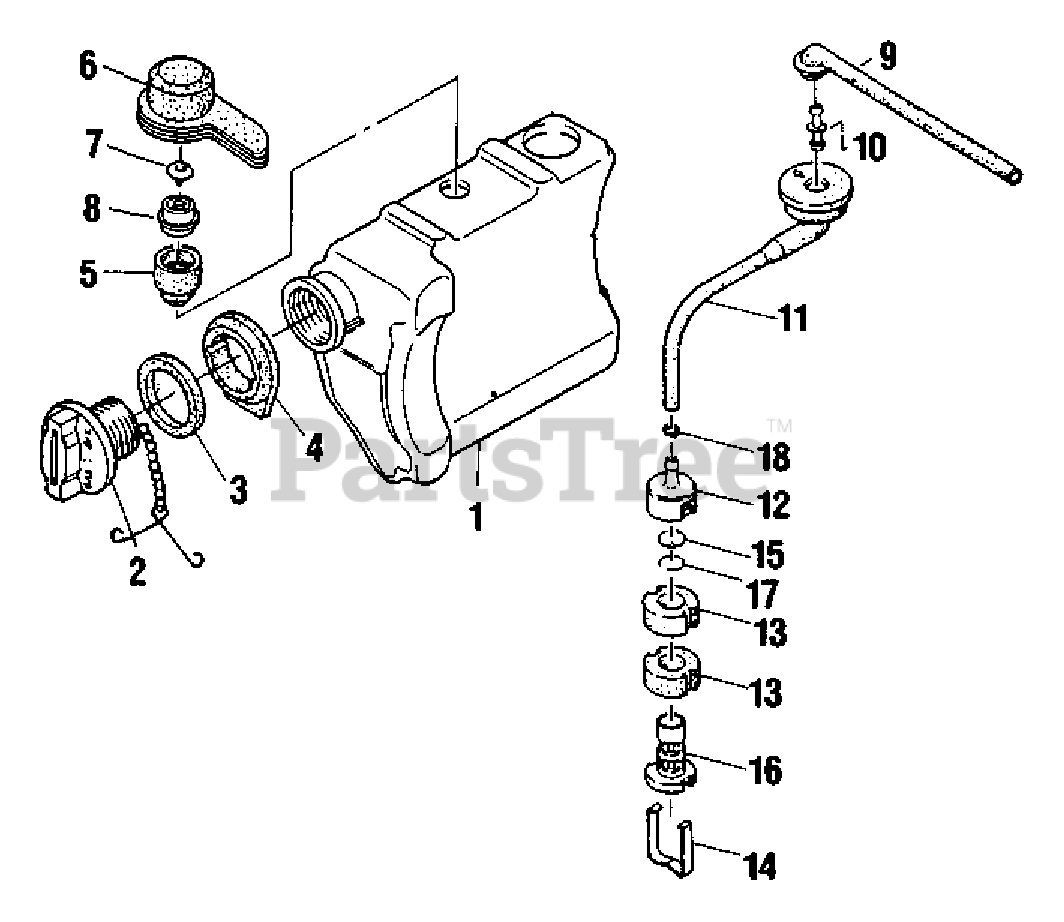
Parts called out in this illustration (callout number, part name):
1	FUEL TANK ASSY
2	CAP ASSY
3	GASKET, CAP
4	SUPPORT, FUEL TANK
5	HOLDER, VALVE
6	CAP, BREATHER
7	VALVE, BREATHER
8	RETAINER, BREATHER
9	PIPE - FUEL
10	CONNECTOR, PIPE
11	PIPE - FUEL
12	WEIGHT, FUEL FILTER
13	FILTER, FUEL
14	CLIP, FILTER
15	SCREEN, FILTER
16	CASE, FILTER
17	RING, RETAINING
18	RING, RETAINING - 6
